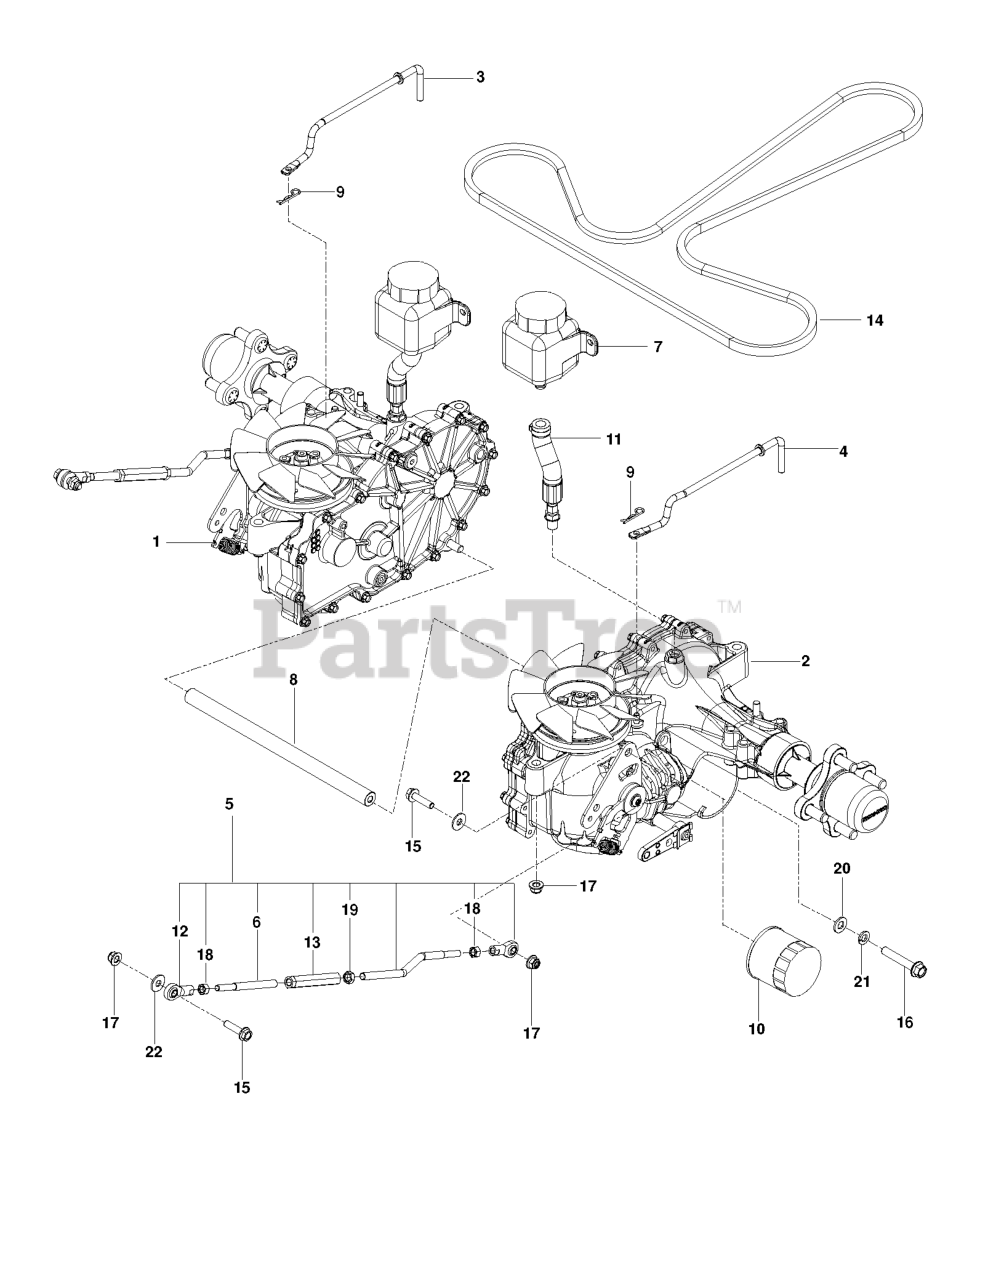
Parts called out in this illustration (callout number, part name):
1	HG_TRANS, ZT-3400, RT
2	HG_TRANS, ZT-3400, LT
3	LINKAGE, RIGHT BYPASS
4	LINKAGE, LEFT BYPASS
5	ASSEMBLY, CONTROL LINKAGE
6	LINKAGE, CONTROL, FT
7	TANK.EXPANSION.350ML 71328
8	SHAFT, TIE ROD
9	HAIRPIN #2
10	HG_FILTER, ZT4800 52114
11	ASSEMBLY, HOSE, EXPANSION
12	BALL JOINT, RIGHT HANDED
13	TURNBUCKLE, 3/8
14	BELT, "AX", 86.7"
15	HHFS 5/16-18 X 1.25 TPBLT GD 5
16	HCS 3/8-16X2-1/4 LOC PATCH GR8
17	5/16-18 NYLOC FLANGE NUT
19	NUT 3/8-24 JAM
20	WASHER 3/8 SAE FLAT
21	SLW 3/8 STD
22	WASHER 5/16 FLAT
